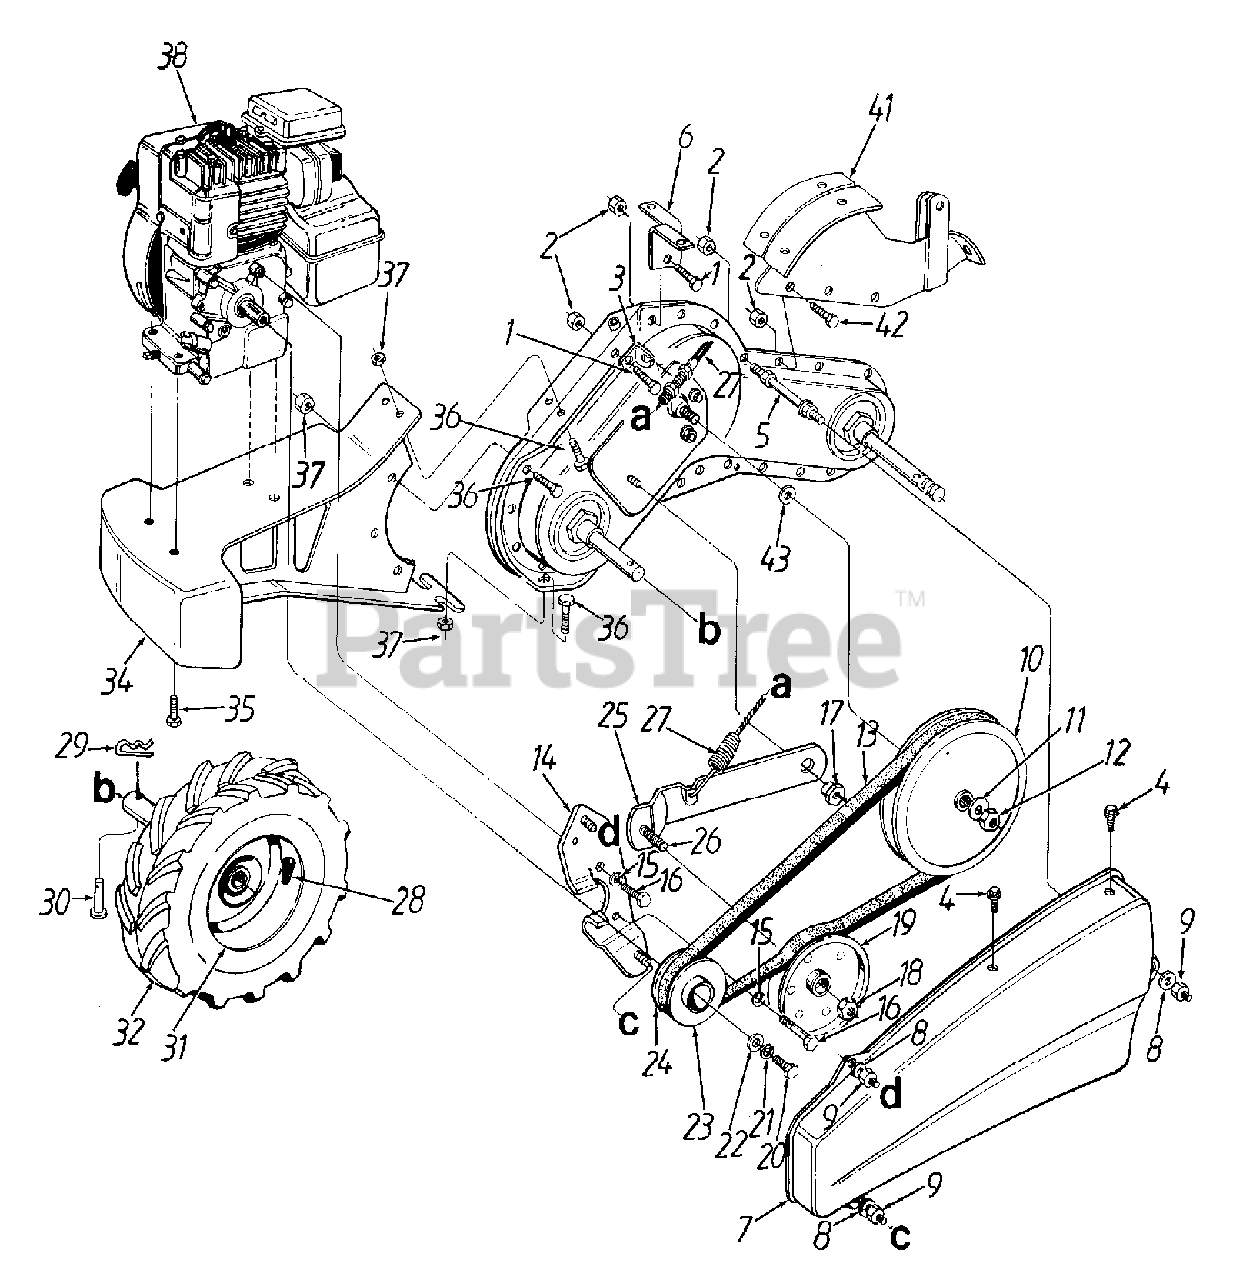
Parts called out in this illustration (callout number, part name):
1	Hex Bolt 5/16-18 x .75" Lg.
2	Hex Top L-Nut 5/16-18 Thd.
3	Cable Mtg. Bracket
4	Torx Mach. AB-Tap Scr. 1/4 x .6" Lg
5	Belt Cover Bolt
9	Hex Cap Nut 1/4-28 Thd.
10	Flat Pulley 8" O.D.
11	Bell-Wash. .38" I.D. x .88" O.D.
12	Hex Flange Nut.
13	"V"-Belt
16	Hex Bolt 5/16-24 x .62" Lg.
17	Shld. Nut
18	Hex Jam L-Nut 3/8-16 Thd.
19	Fl-Idler w/Flanges
20	Hex Bolt 3/8-24 x 1" Lg.
21	L-Wash. 3/8" I.D.
22	Fl-Wash. 3/8" I.D. x 1" O.D.
23	Outer Engine Pulley Half
24	Inner Engine Pulley Half
26	Hex Bolt 3/8-16 x 1.25" Lg.
27	Clutch Cable
28	Air Valve
29	Hairpin Clip
30	Clevis Pin
34	Frame Counterweight
35	Hex TT-Tap Scr. 3/8-16 Thd.
36	Hex Bolt 5/16-18 x 1" Lg. (Gr. 5)
37	Hex Flange L-Nut 5/16-18 Thd.
38	Engine
43	Wash. Fl..635 I.D. x .930 O.D. x .03
